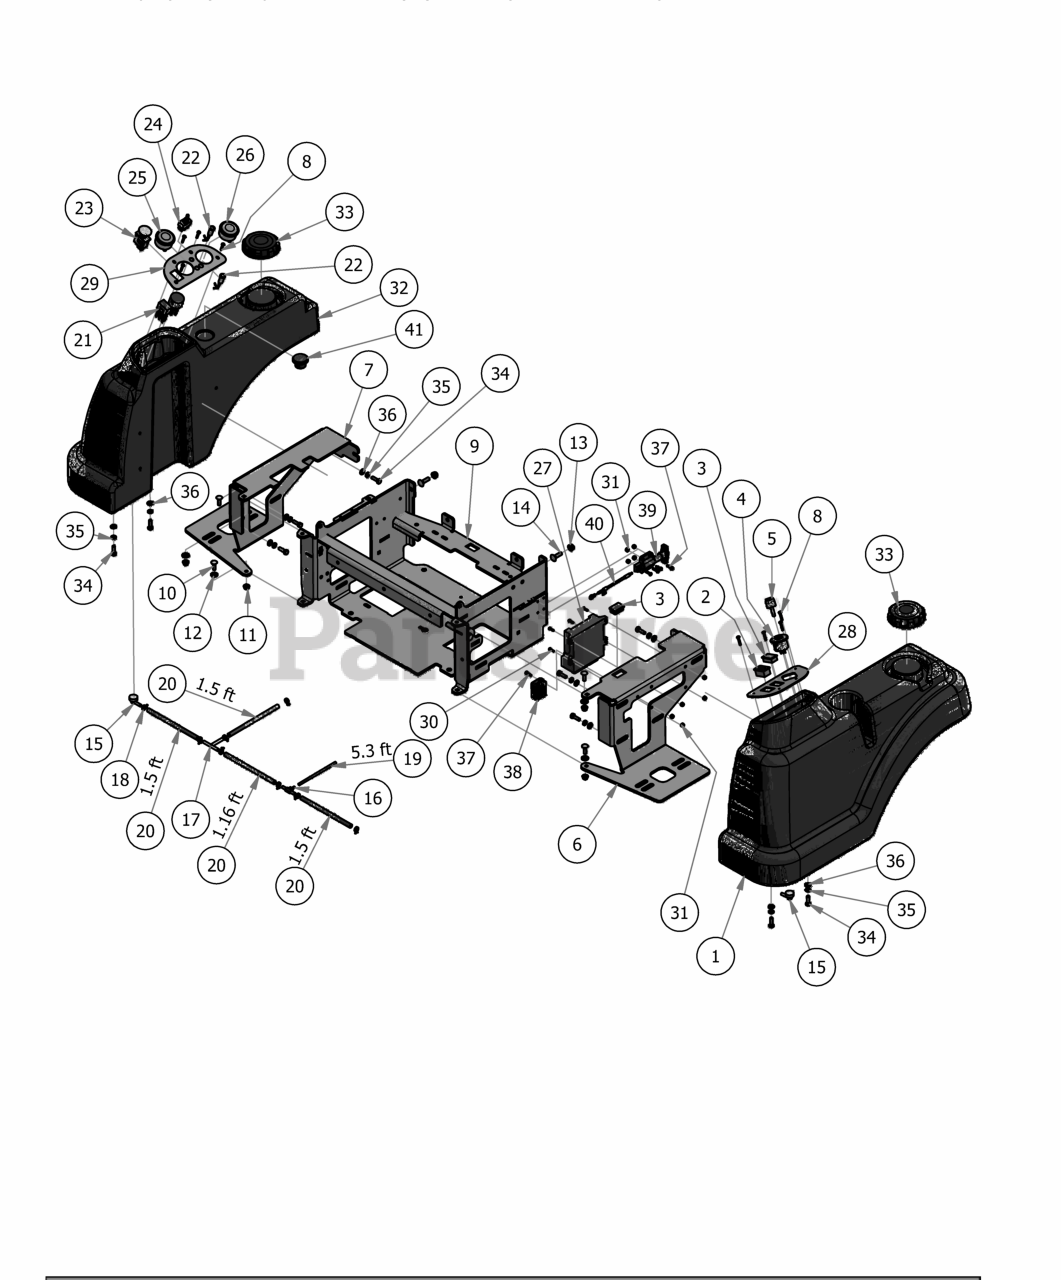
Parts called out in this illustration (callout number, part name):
1	Left Fuel Tank with Fender
2	Hour Meter
3	Light Plug
4	Ignition Switch
5	Ignition Key
6	Tank Supports-Left
7	Tank Support- Right
8	10-32 x 1 Button Head Bolt
9	Diesel Seat Frame
10	5/16" x 1" Carriage Bolt
11	5/16" Flange Nut
12	.360 ID Plastic Washer
13	3/8" Nylock Flange Nut
14	3/8" x 1 1/4" Carriage Bolt
15	Fuel Tank Hose Nipple w/ Filter
16	Brass fuel line T
17	fuel line T
18	1/4 Fuel Hose Clamp
19	3/16 Fuel Line
20	1/4" Fuel Line Hose
21	Wiring Harness
23	PTO Engager
24	Deck Lift Joystick
25	2" Water Temperature Gauge
26	2" Oil Pressure Gauge
27	ECM for 1100cc Diesel
28	Control Panel (Left)
29	1100cc Diesel Control Panel
30	10-24 X 5/8 BS Button Head Bolt
31	10-24 Nylon Insert Locknut Zinc Orange Nylon
32	Right Fuel Tank with Fender
33	Diesel Fuel Cap - 3.5" Neck
34	5/16" x 1" Bolt
35	5/16" Lock Washer
36	5/16" Flat Washer
37	10-24 x 1 BS C/S 18-8 SS
38	Auto Shut Down for Cat Diesels
39	2016 T Handle Release
40	2015 Seat Latch Cable
41	Fuel Gauge and Grommet
